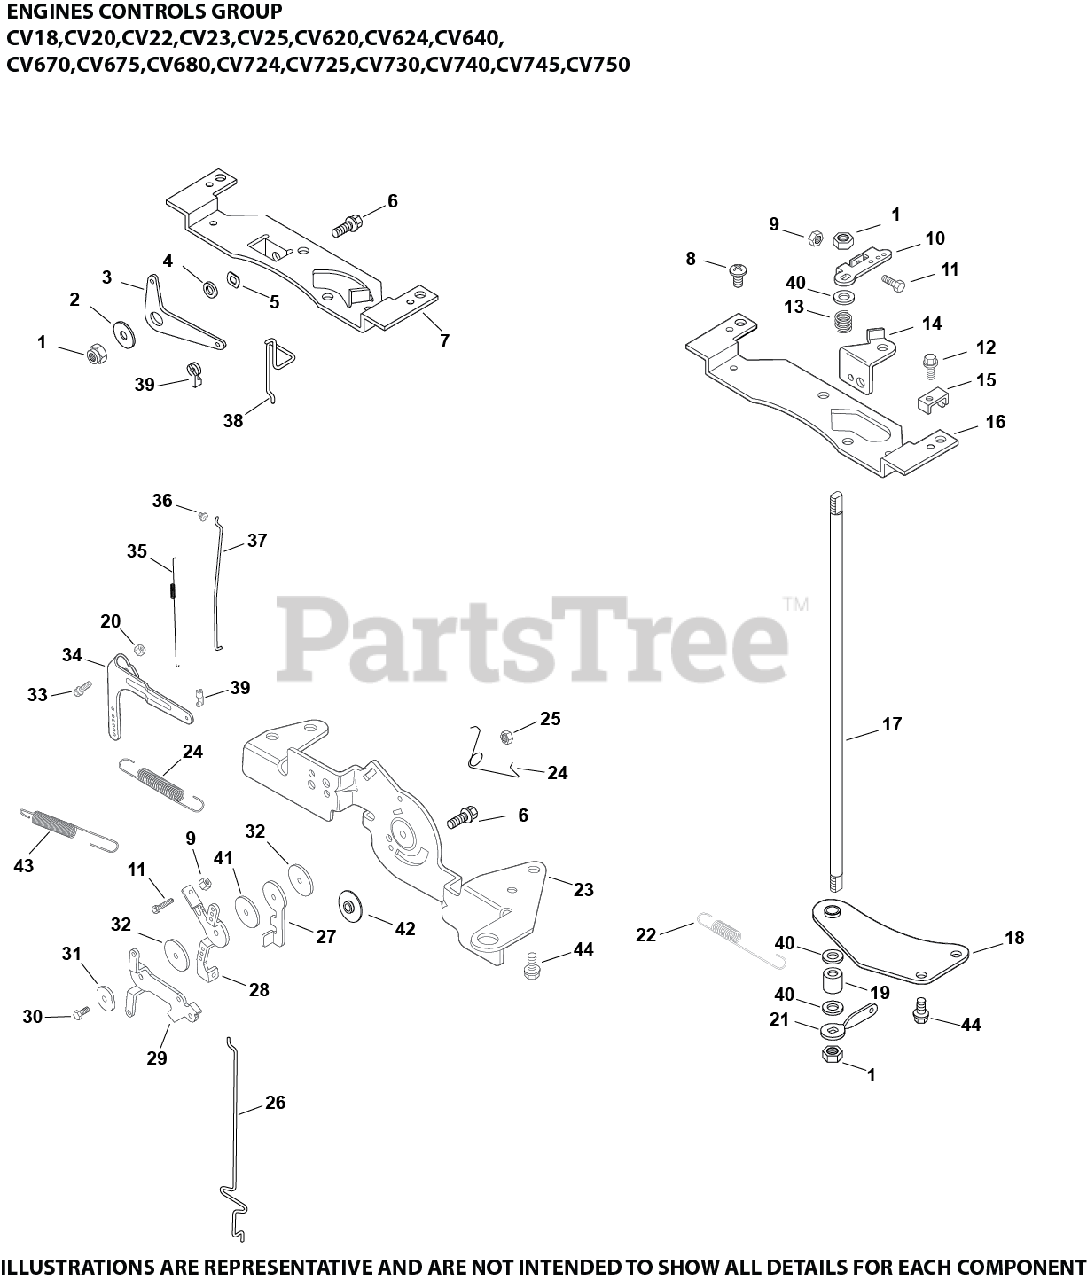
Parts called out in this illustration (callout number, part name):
9	NUT, M4X0.7
11	SCREW, SLT HD CAP M4X0.7X25
12	SCREW, THREAD FORMING
15	CLAMP, CABLE
20	NUT, FLG M6X1.0
22	SPRING, GOVERNOR (ORANGE)
23	BRACKET, CONTROL - (#3212604S)
24	SPRING, CHOKE RETURN
25	NUT, LOCK M5X.8
26	LINKAGE, CHOKE
27	LEVER, THROTTLE ACTUATOR
28	LEVER, THROTTLE CONTROL
29	LEVER, CHOKE
30	SCREW, THREAD FORMING - USE 25 086 473-S
31	WASHER, SPRING 1/4"
32	WASHER, FLAT 5.5 MM
33	BOLT, RD HD SQ NECK M6X1.0X25
34	LEVER, GOVERNOR ASSEMBLY
35	SPRING, LINKAGE
36	BUSHING, LINKAGE RETAINING
37	LINKAGE, THROTTLE
39	BUSHING, THROTTLE LINKAGE
40	WASHER, FLAT 1/4"
41	WASHER, FLAT 5.5 MM
44	SCREW, THREAD FORMING
